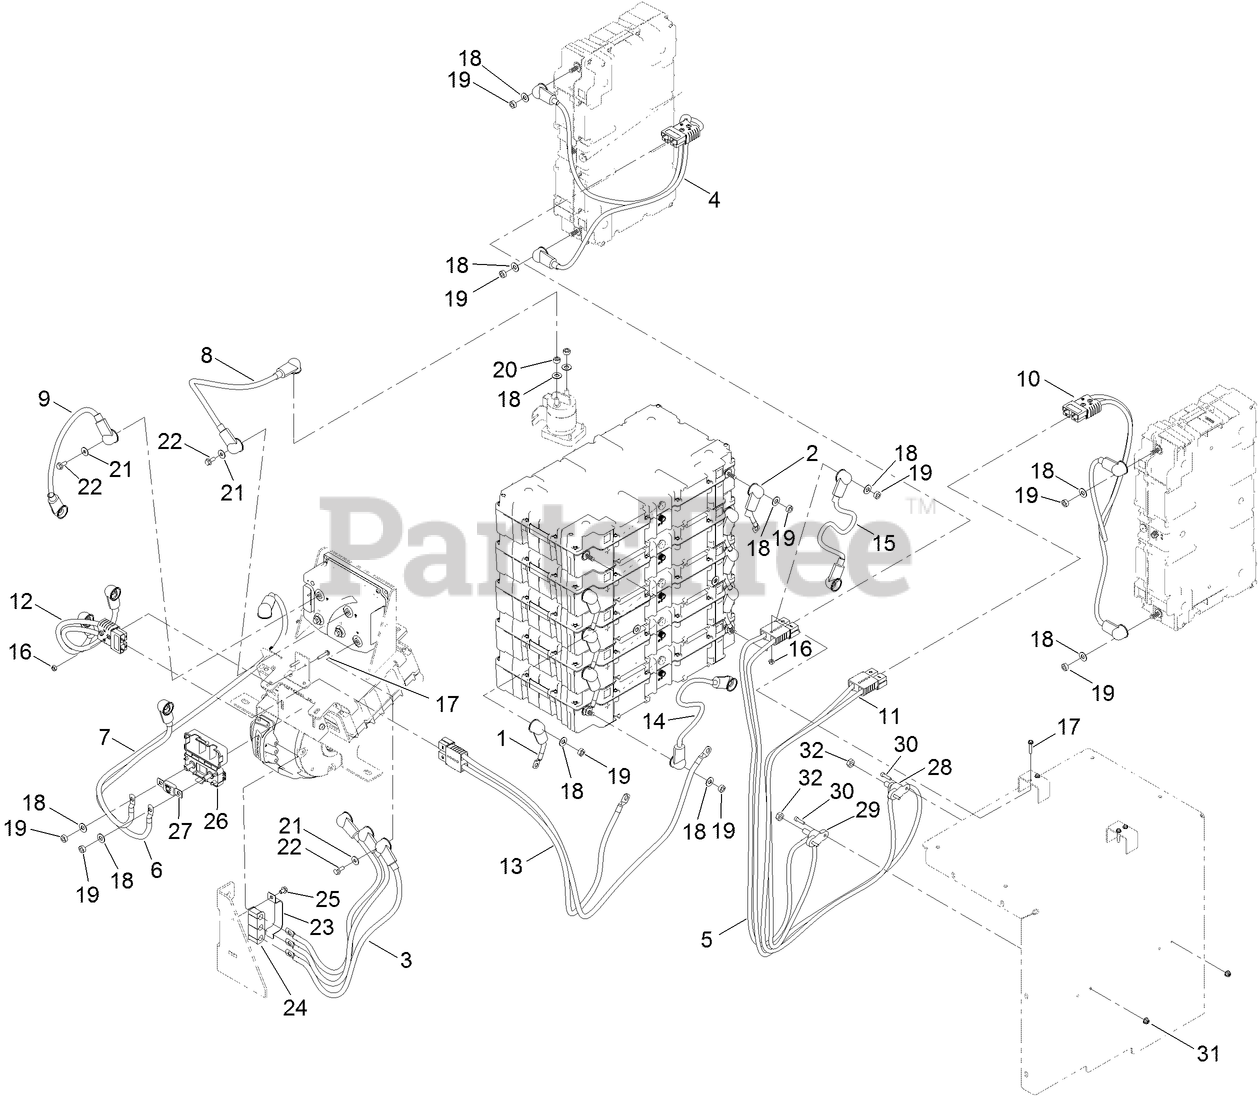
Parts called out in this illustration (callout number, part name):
1	CABLE-BATTERY,POSITIVE ASM
2	CABLE-BATTERY,NEGATIVE ASM
3	CABLE-BATTERY, RD ASM
4	CABLE-BATTERY, RD/BK ASM
5	CABLE-BATTERY, RD/BK ASM
6	CABLE-BATTERY, RD ASM
7	CABLE-BATTERY, RD ASM
8	CABLE-BATTERY, RD ASM
9	CABLE-BATTERY, BK ASM
10	CABLE-BATTERY, RD/BK ASM
11	CABLE-BATTERY, RD/BK ASM
12	CABLE-BATTERY, RD/BK ASM
13	CABLE-BATTERY, RD/BK ASM
14	CABLE-BATTERY, RD ASM
15	CABLE-BATTERY, BK ASM
16	NUT-LOCK, NI
17	SCREW-HWH
18	WASHER
19	NUT-HEX
21	WASHER
22	SCREW-HHF
23	RETAINER-ISOLATOR
24	ISOLATOR-CLAMP
25	SCREW-HWH
26	HOLDER-FUSE, MEGA
27	FUSE-200 AMP
28	BLOCK-JUNCTION
29	BLOCK-JUNCTION
30	SCREW-HSH
31	NUT-HF
32	NUT-HEX
